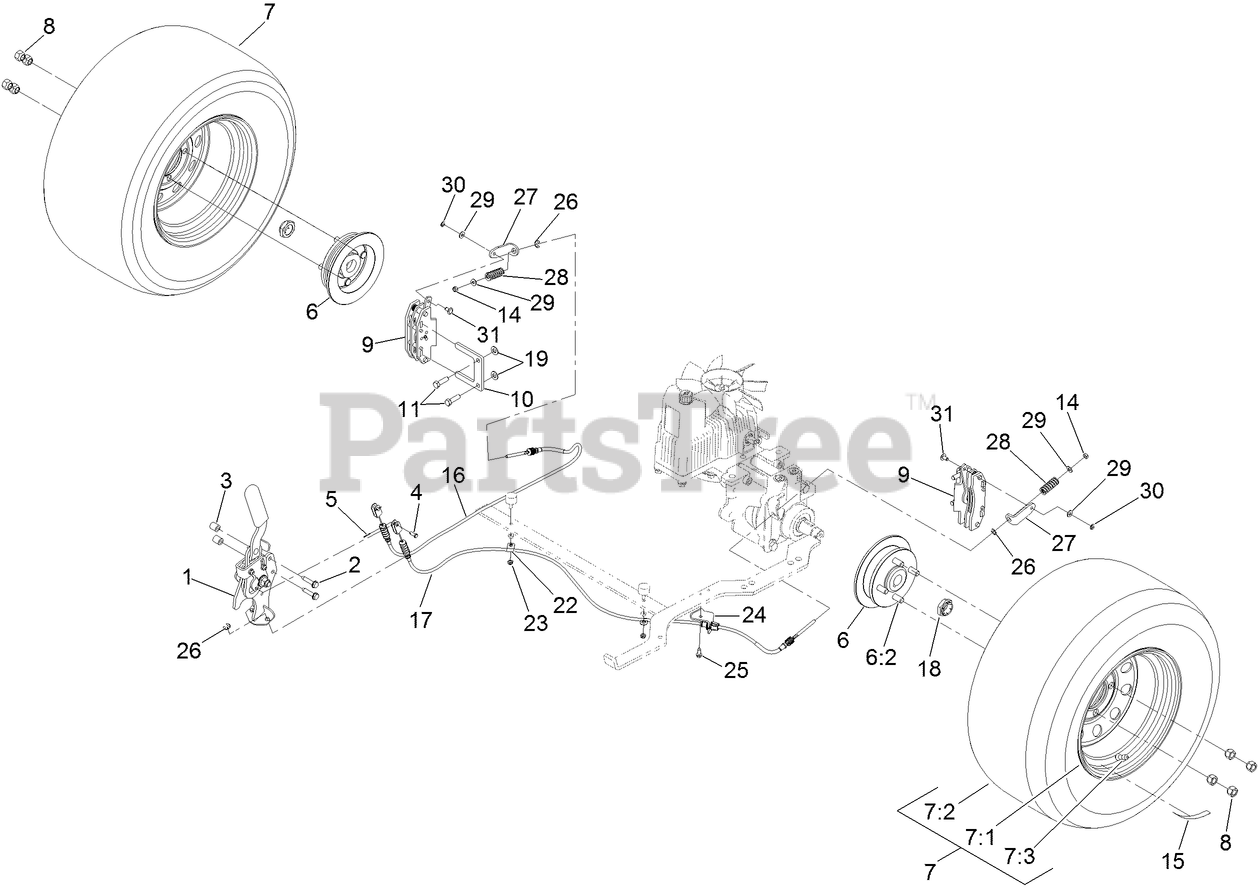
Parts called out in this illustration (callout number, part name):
1	BRAKE HANDLE ASM
3	SPACER
4	PIN-CLEVIS
5	PIN-COTTER
6	WHEEL HUB ASM
6:2	STUD-WHEEL
7	WHEEL AND TIRE ASM
7:1	RIM ASM
7:2	TIRE
7:3	STEM-VALVE
8	NUT-LUG
9	CALIPER-BRAKE
10	PLATE-MOUNT, BRAKE
11	SCREW-LOCK, PATCH
14	NUT-LOCK, NI
15	DECAL-WHEEL NUT TORQUE
16	CABLE-PARK BRAKE, RH
17	CABLE-PARK BRAKE, LH
18	LOCKNUT
19	WASHER-FLAT
23	NUT-LOCK, NI
24	BRACKET-CABLE
25	SCREW-HWH
26	E-RING
27	BRACKET-BRAKE, L
28	SPRING-DIE
29	WASHER-FLAT
30	E-RING
31	PIN-BRAKE
